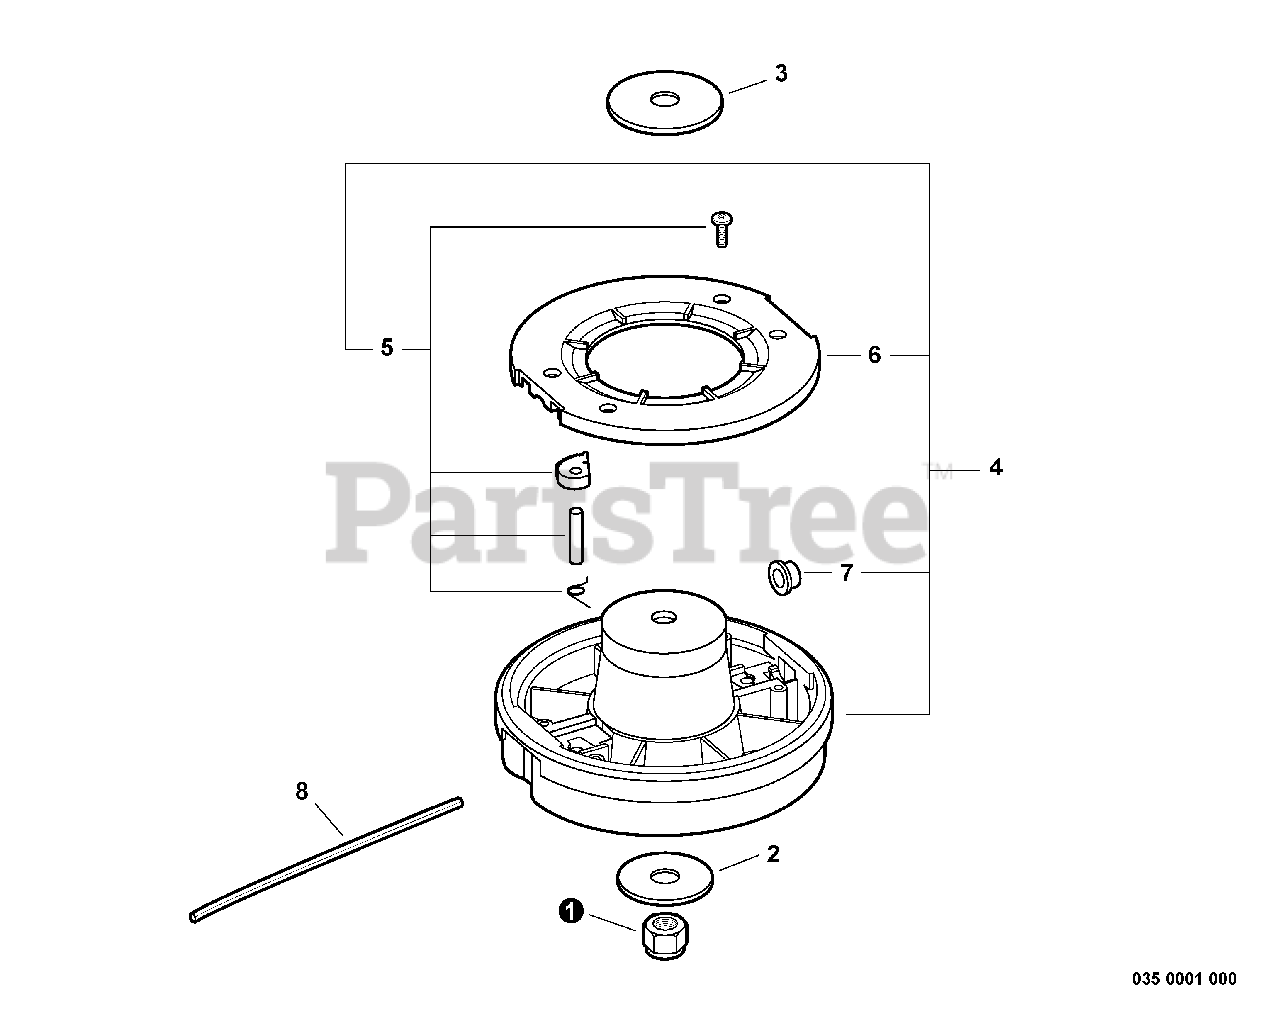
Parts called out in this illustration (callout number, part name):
1	NUT, LOCK
2	WASHER 10
4	TRIMMER HEAD, RAPID-LOADERT- 2 LINE
5	PAWL KIT
6	COVER, TOP
7	EYELET (PACKAGE OF 3)
8	LINE, TRIMMER - 0.080 DIA. (PKG. OF 20)
